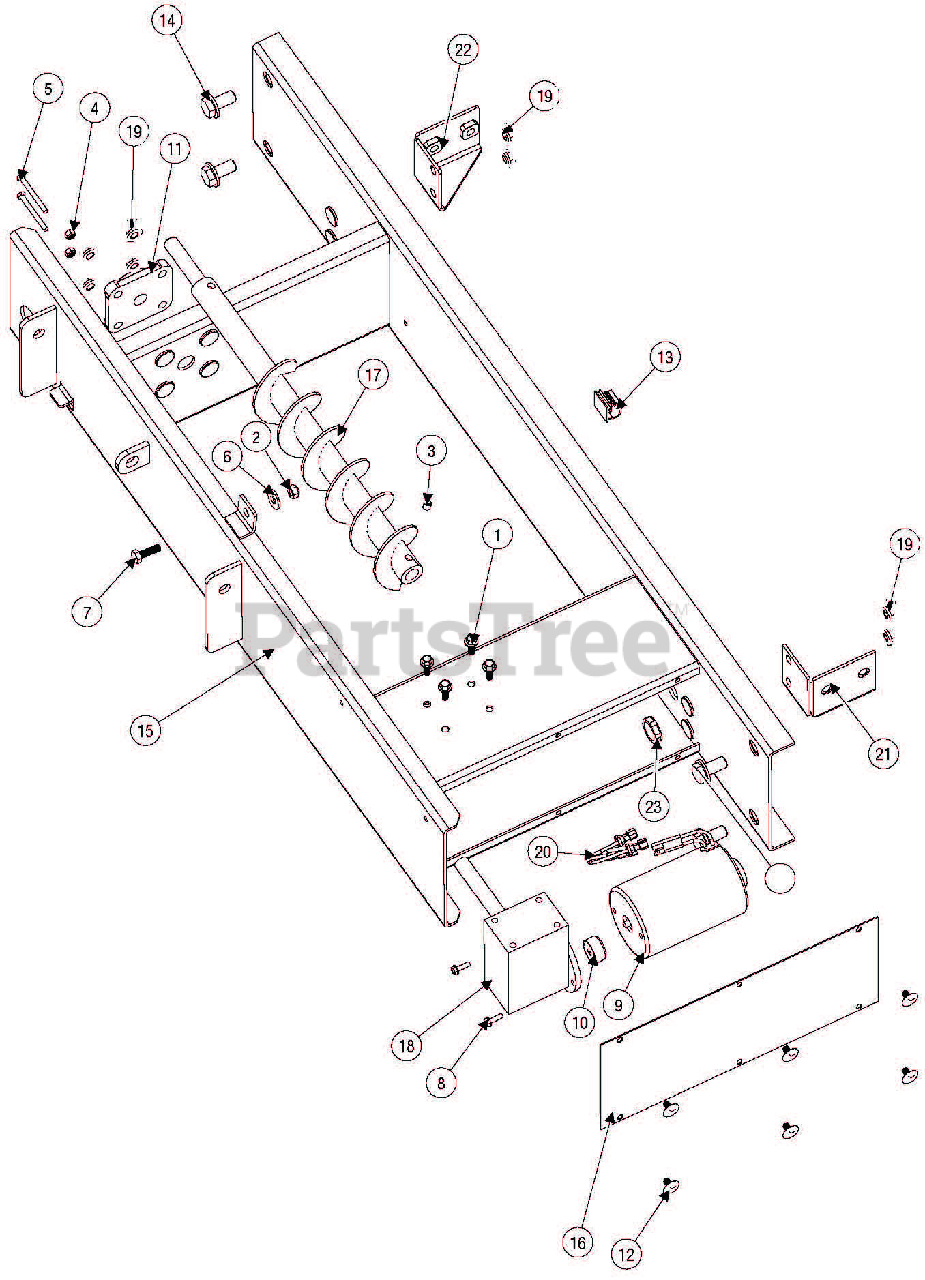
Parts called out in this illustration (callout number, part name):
3	SET SCREW
8	BOLT, #10-32 X 5/8 SERRATEDFLANGE, ZINC, W/PATCH (5PK)
9	MOTOR 3.0 X 3.8 12 VOLT DC
10	MOTOR DRIVE COUPLER
11	BEARING 5/8-IN 4 BOLT FLANGE
12	RETAINER, 1/4 X 3/4 X 1/2 6 PK
13	CLAMP, 3/8 WIRE LOOM
15	AUGER DRIVE WELDMENT PRO TRUCK
16	AUGER MOTOR COVER PRO TRUCK
17	AUGER, 2-5/8 X 20 X 2
18	TRANSMISSION 30:1 WORM GEAR
20	MOTOR CONNECTOR ADAPTER D6320
21	LOWER RAIL MOUNT BRACKET PS
22	LOWER RAIL MOUNT BRACKET DS
23	NUT, 5/16-18 BLACK NYLON2PK
